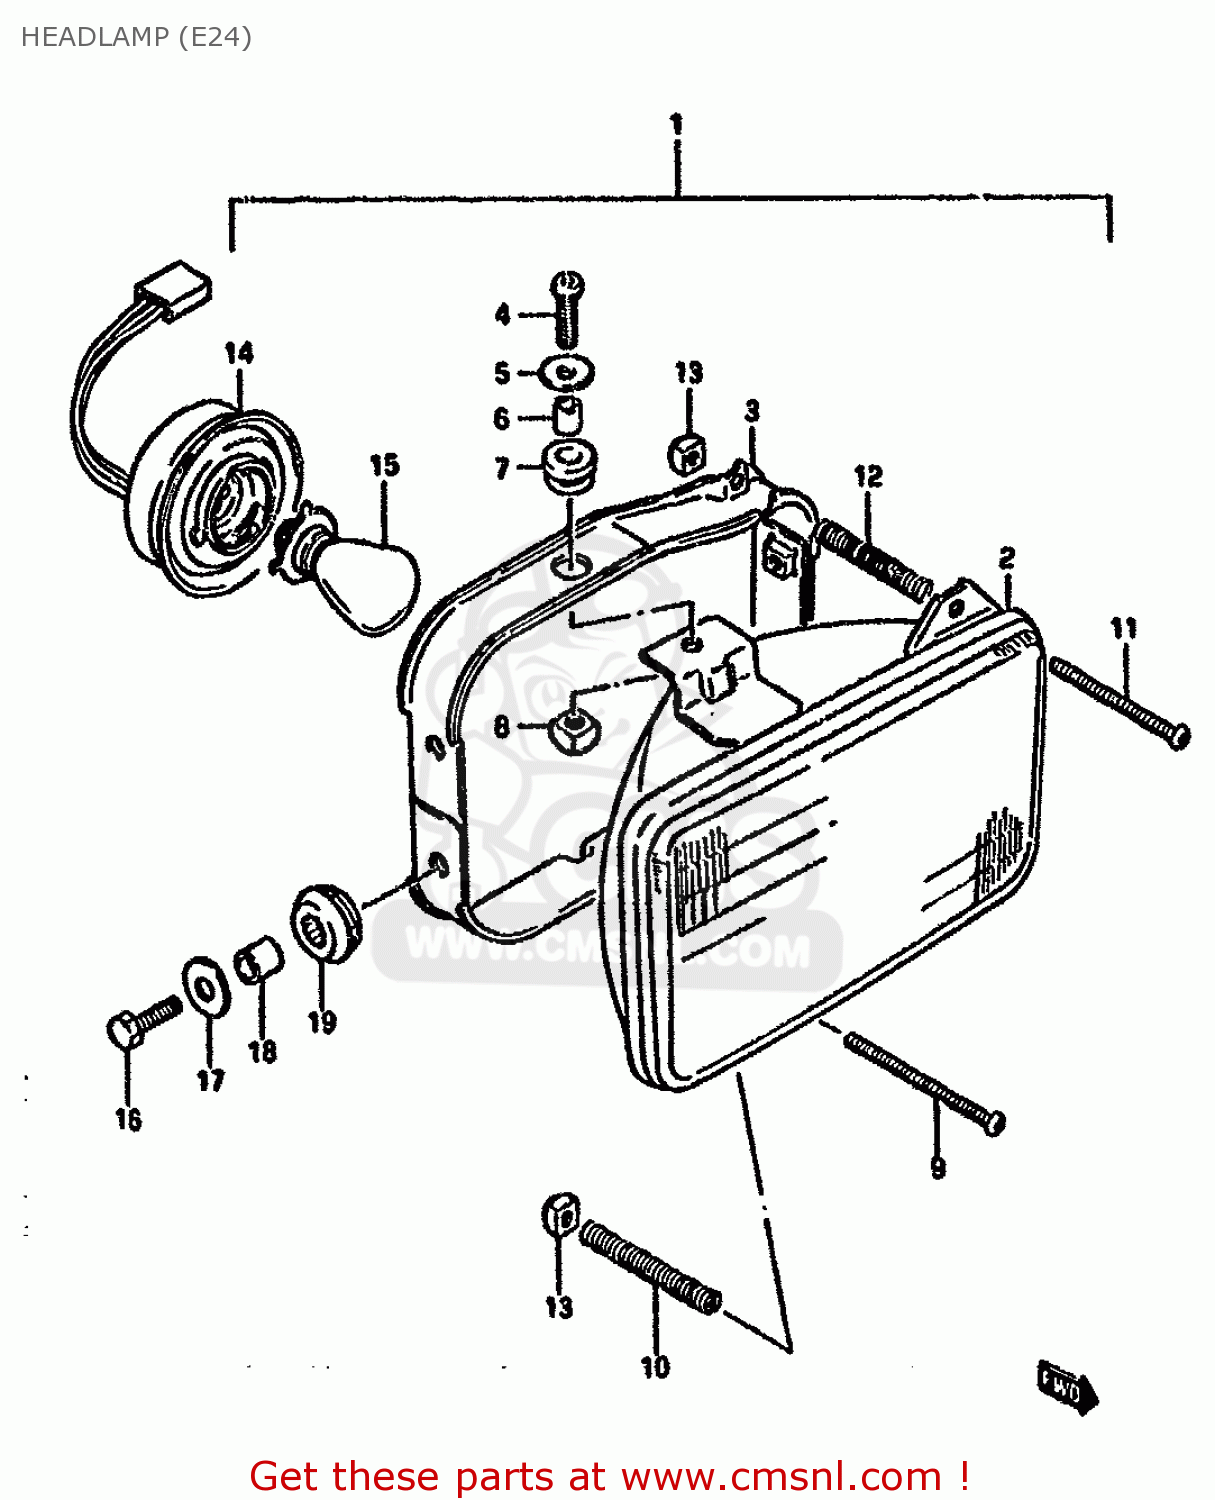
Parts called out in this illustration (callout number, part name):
1	HEADLAMP ASSY
2	UNIT
3	HOUSING
4	SCREW(5X14)
5	WASHER
6	SPACER
7	CUSHION
8	NUT
9	SCREW,HEADLAMP ADJUST
10	SPRING
11	SCREW,HEADLAMP ADJUST
12	SPRING
13	NUT
14	SOCKET,HEAD LAMP
15	BULB(12V45/45W,STANLEY,70281A)
16	BOLT
17	WASHER (6.5X20X1.2)
18	SPACER (6.1X9X9)
19	CUSHION
